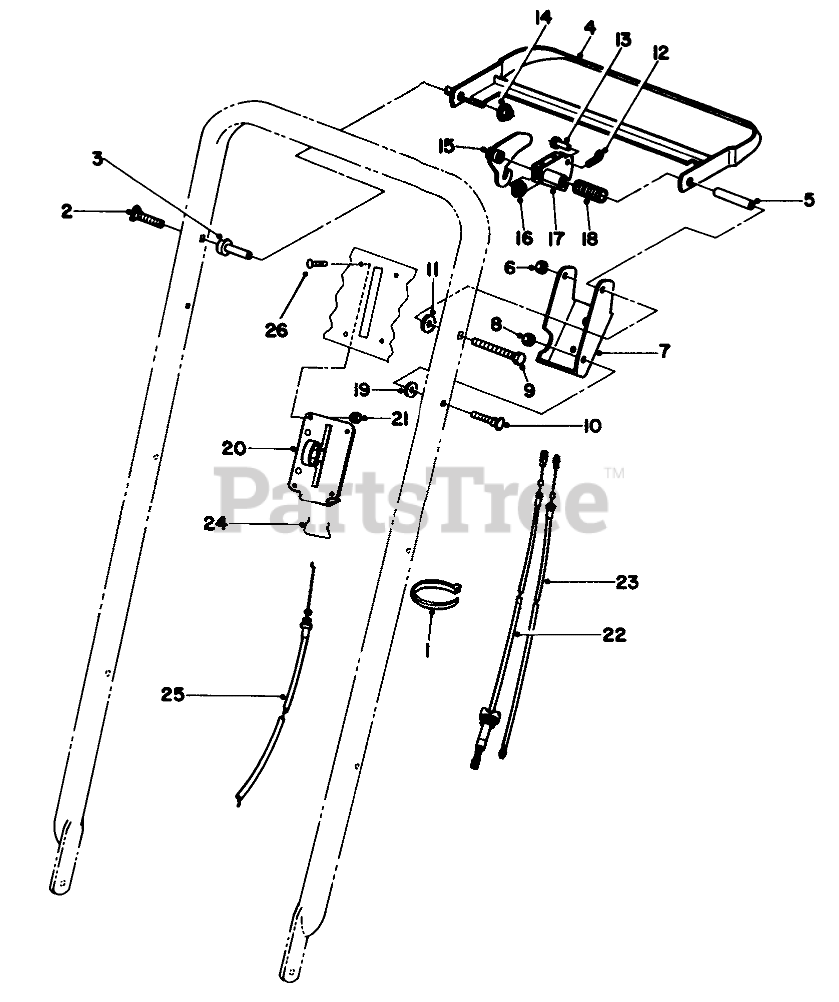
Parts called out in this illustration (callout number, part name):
1	TIE-CABLE
2	SCREW
3	SPACER-SUPPORT
4	Bar-Control
5	SPACER-BRACKET, CONTROL
6	NUT-LOCK, NI
7	CONTROL BRACKET
8	NUT-LOCK, NI
9	SCREW-HH
10	SCREW-HANDLE
11	SPACER
12	PIN-COTTER
13	PIN-CABLE
14	NUT-LOCK, NI
15	LEVER-TRACTION
16	BUSHING-FLANGE
17	LEVER-BBC
18	SPRING-CONTROL
19	SPACER
20	CONTROL-THROTTLE
21	NUT-LOCK, NI
22	CABLE-TRACTION
23	CABLE-CLUTCH
24	RETAINER-CABLE, THROTTLE
25	CABLE-THROTTLE
26	SCREW-PPH
